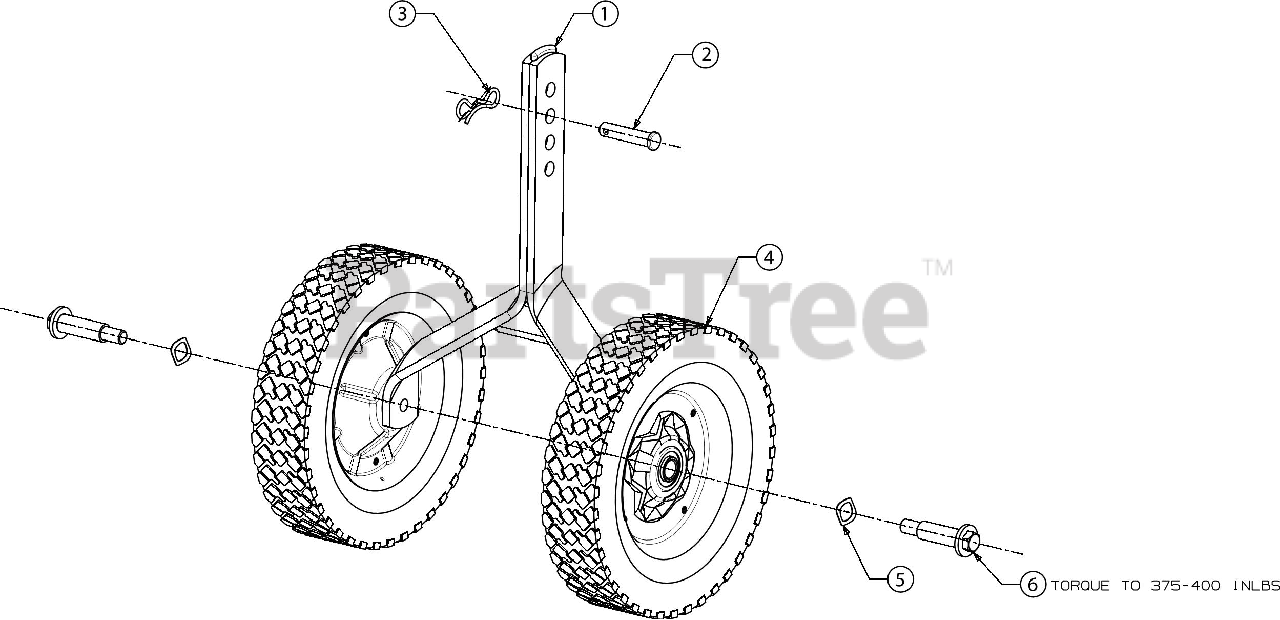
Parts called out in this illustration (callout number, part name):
1	WHEEL BRACKET ASSEMBLY
2	CLEVIS PIN .375 X .1.75
3	PIN:COTTER
4	TIRE & WHEEL ASSEMBLY
5	WAVE WASHER
6	SHOULDER SCREW .496X1.44 3/8-16
